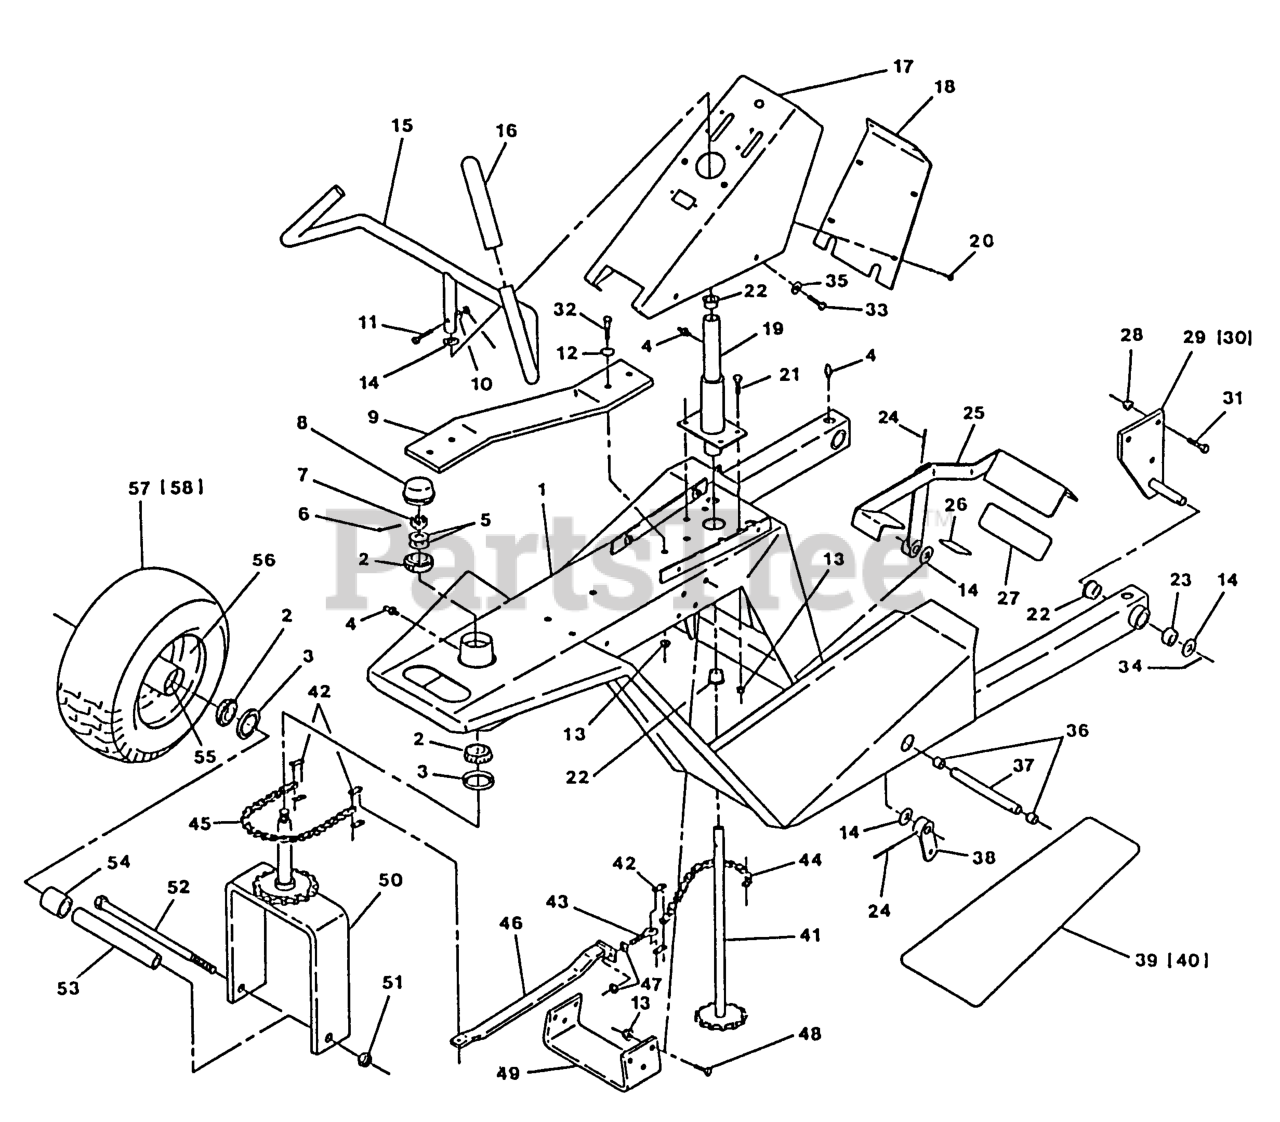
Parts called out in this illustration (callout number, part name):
2	Cone-Bearing Tapered Roller
3	SEAL-GREASE
8	CAP-GREASE
23	SLEEVE,BEARING
24	PIN,ROLL
27	PAD,ANTISKID
29	WLD,BRACKET PIVOT RH
30	WLD,BRAKCET PIVOT LH
38	WLD,FOOT PEDAL LEVER
39	PAD,ANTISKID RH
40	PAD,ANTISKID LH
43	EYEBOLT, RH
49	STOP,ACTUATOR
52	SCRW,CAP HH
53	BUSHING, WHEEL - PLT
54	SPACER,WHEEL SHORT
55	CUP-BEARING
56	WHEEL 8.00 W/HUB
57	ASM,WHEEL & TIRE
58	TIRE ONLY 8NHS
